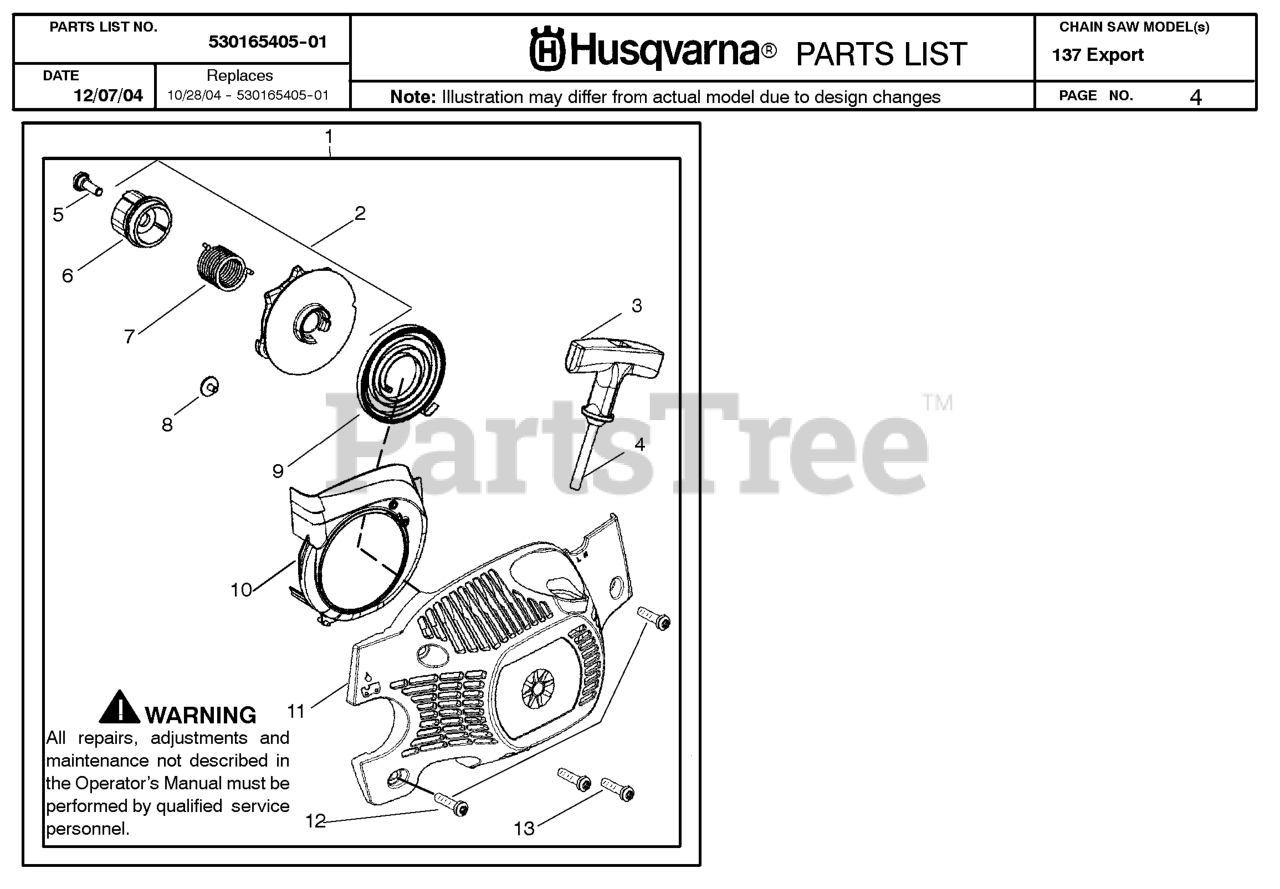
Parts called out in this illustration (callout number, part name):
1	KIT FAN HSG & STARTER EPS
2	KIT EPS STARTER
3	STARTER HANDLE
5	SCREW SHOULDER
6	HUB STARTER EPS
7	SPRING EPS
8	SCREW SEMS TOOTHED WASHER
9	SPRING STARTER
10	BAFFLE AIR
11	HOUSING FAN W/ EYELET
13	SCREW,STRTR CVR 36/41
